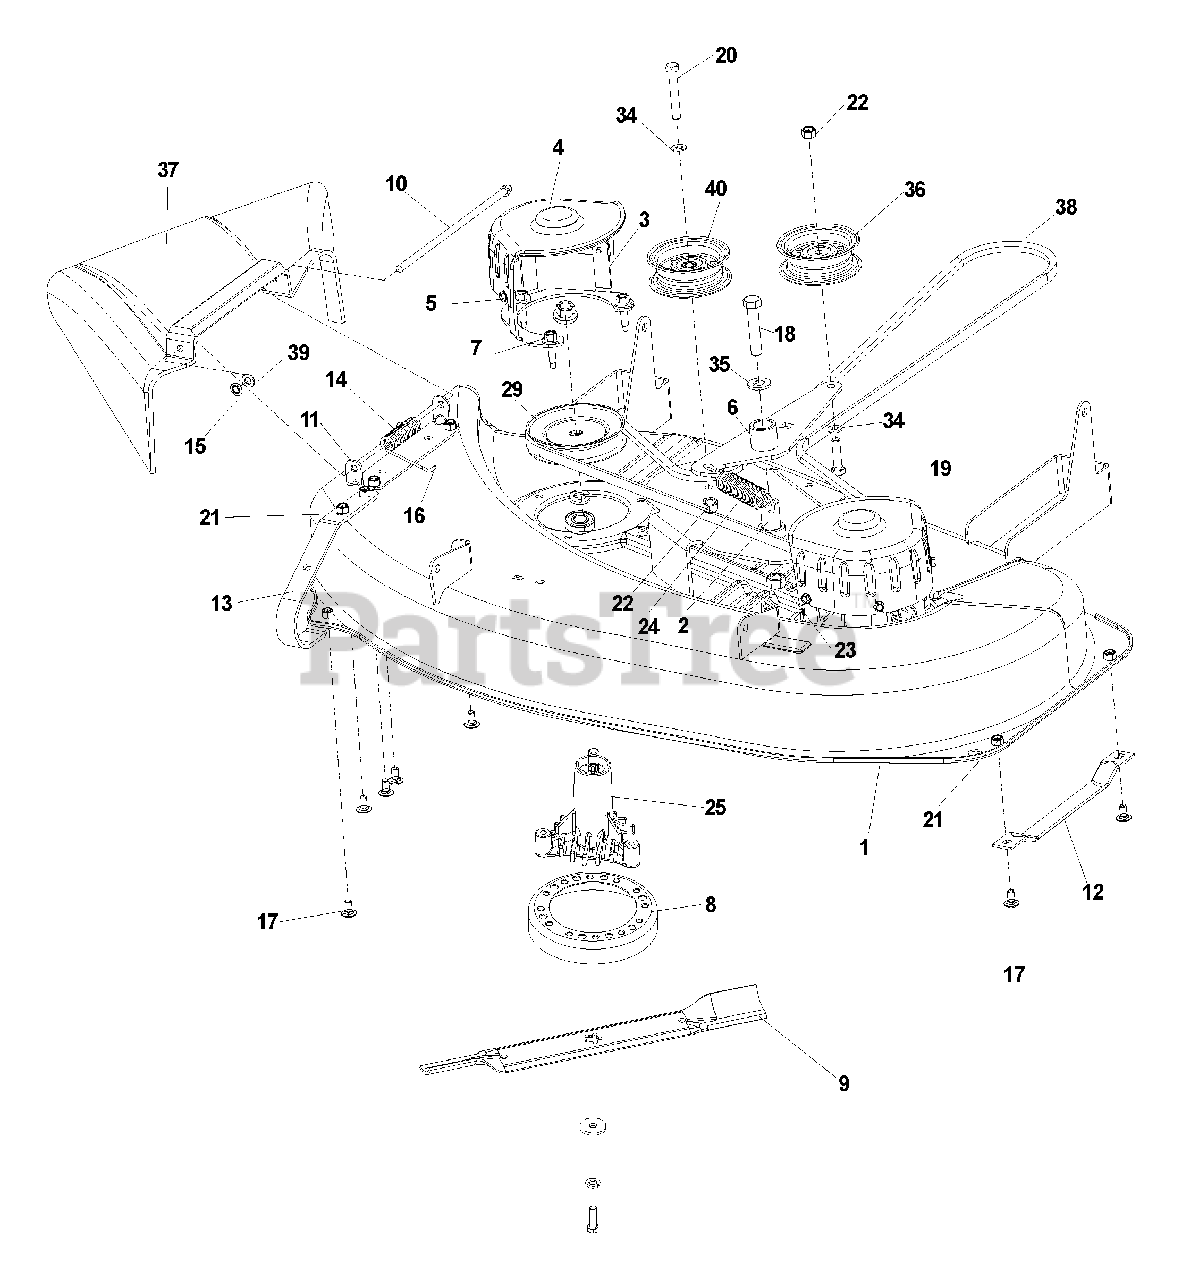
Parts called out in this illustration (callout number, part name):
1	DECK W/DECAL, 38"
2	IDLER SPINDLE
3	SPINDLE COVER ANCHOR
4	SPINDLE COVER
5	SCREW, 1/4C X 5/8, SELF TAPPING
6	DECK IDLER ARM
7	SCREW, WASHER HEAD
8	STRIPPER, ROUND, UNIVERSAL
9	BLADE, 38", MULCHING
10	ROD, HINGE
11	BRACKET, MOWER DEFLECTOR
12	RUNNER, LEFT
13	RUNNER, RIGHT
14	SPRING, TORSION, DEFLECTOR
15	PUSHNUT
16	CAP-SLEEVE
17	RHSNB 5/16-18 X 5/8, GR5
18	HCS 1/2-13 X 2 3/4, GR5
19	HCS 3/8-16 X 1 1/2, GR5
20	HCS 3/8-16 X 2 1/2, GR5
21	NUT, 5/16C, NYLOC
22	NUT, 3/8C, NYLOC
23	NUT, 1/2C, NYLOC
24	TRACTION SPRING
25	HOUSING, MANDREL, ASSY
29	PULLEY, MANDREL
34	WASHER, 3/8, SAE
35	WASHER, 1/2, SAE
36	PULLEY, DECK IDLER
37	SHIELD DEFLECTOR
38	BELT, 38" DECK
39	WASHER, 11/32 X 5/8 X 16GA
40	PULLEY, IDLER
